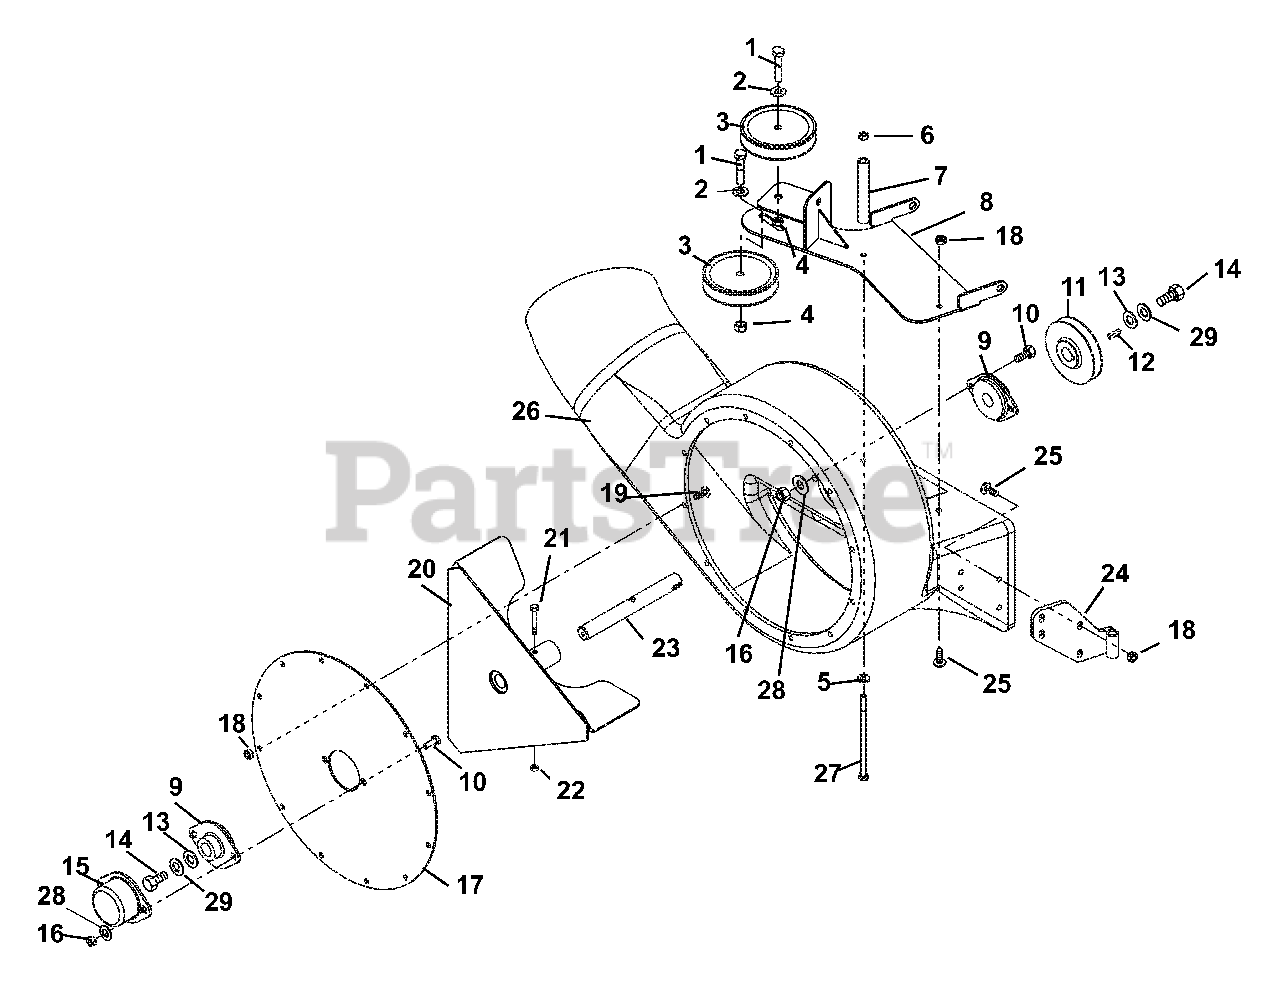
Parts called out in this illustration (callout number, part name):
1	@BLT-HEX .38-16X1.50 GR5 YWZC
2	@WSHR-FL-STL.38X.875X.083 YWZC
3	IDLER-V 4.00 X .38 NWHAMSHR
4	@NUT-SPNLK-FLG .375-16 YWZC
5	@WSHR-FL-STL.281X.62X.065 YWZC
6	@NUT-LK-CTR .25-20 YWZC
7	SPACER .334X.500X4.625
8	BRACKET COMP-MULE PULLEY
9	BEARING, 2 BOLT FLANGE -.75 ID
10	@BLT-HEX .31-18X1.00 GR5 YWZC
11	PULLEY, DRIVEN 3.50
12	KEY-SQ .187 X .50 X .187
13	WSHR-FL-STL .328X1.0X.094 YWZC
14	BLT-HEX .25-28X.75 GR5 YWZC
15	COVER-BEARING
16	@NUT-LK-NYL .312-18 YWZC
17	PLATE-BEARING MOUNTING
18	@NUT-SPNLK-FLG .25-20 YWZC
19	SCR-MCH .25-20X.50 TXTR PL
20	IMPELLER, GRASS PUMP
21	@BLT-HEX .25-20X1.50 GR5 YWZC
22	@NUT-LK-CTR .25-20 YWZC
23	SHAFT, GRASS PUMP - .75 OD
24	MOUNTING BRACKET COMPLETE
25	SCR-MCH .25-20X.75 TXTR YWZC
26	HOUSING, BLOWER
27	@BLT-HEX .25-20X6.00 GR5 YWZC
28	@WSHR-FL-STL.312X.734X.065 YWZ
29	@WSHR-LK .25X.062 REG YWZC
